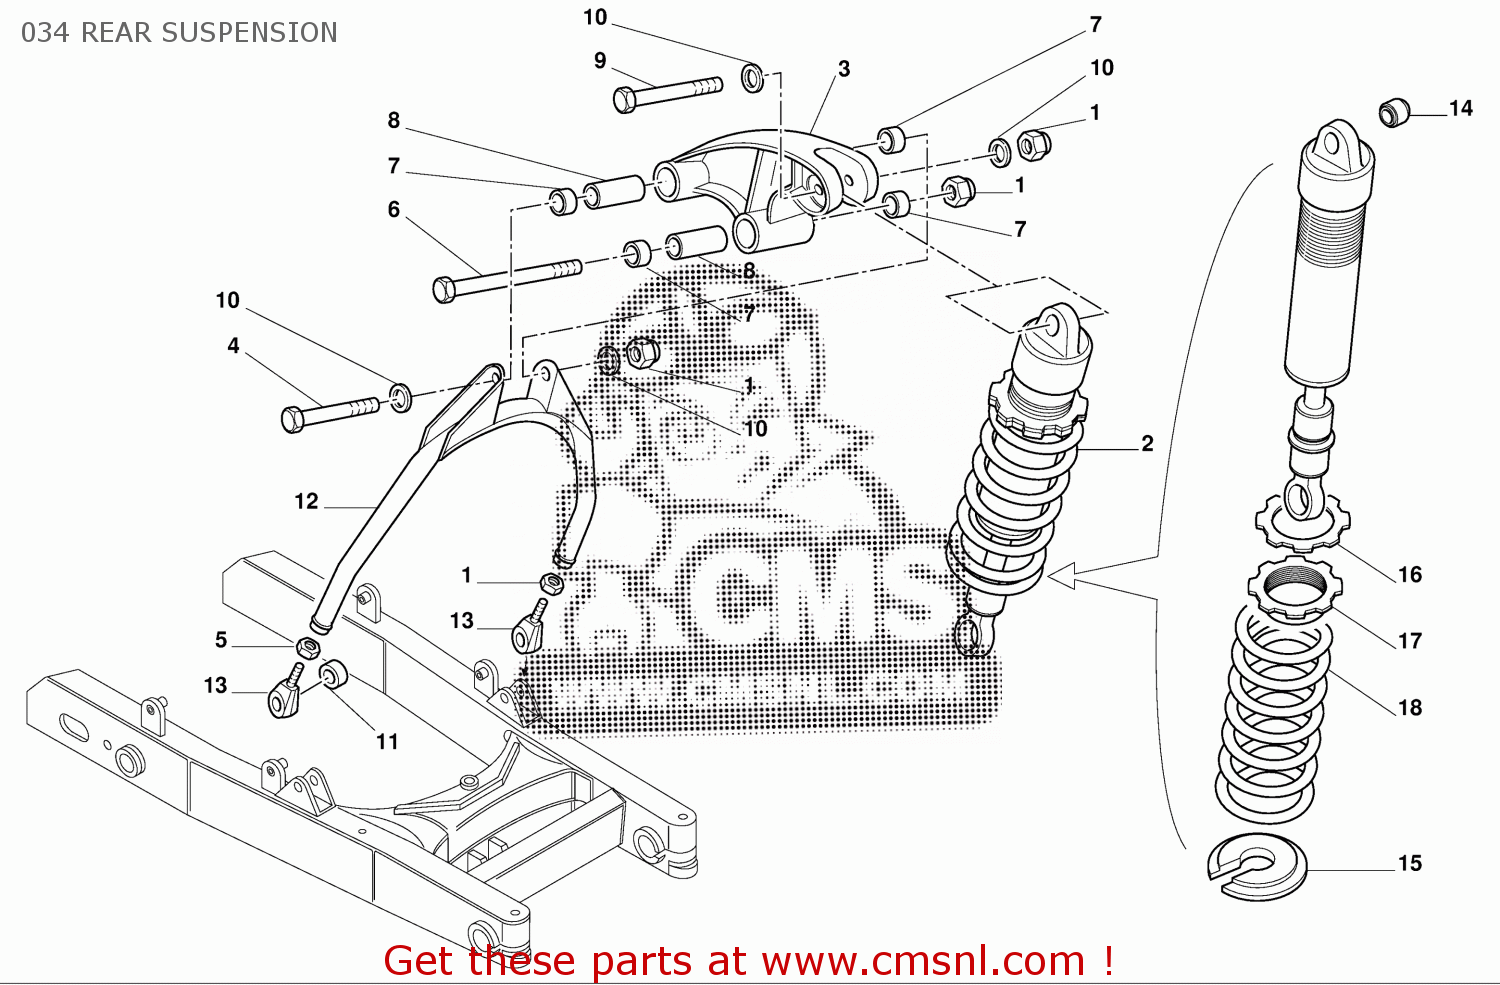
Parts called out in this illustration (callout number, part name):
1	NUT
2	SHOCK-ABSORBER
3	ROCKER ASSEMBLY
4	SCREW M10X95
5	NUT M10
6	SCREW M10X135
7	NEEDLE CAGE
8	SPACER
9	SCREW, SPECIAL
10	WASHER, THRUST
11	BUSH 8X10X13
12	BOW, ASSY
13	BALL JOINT
14	BALL JOINT
15	SPRING SEAT
16	RING NUT
17	RING NUT
18	SPRING, SHOCK ABSORBER
